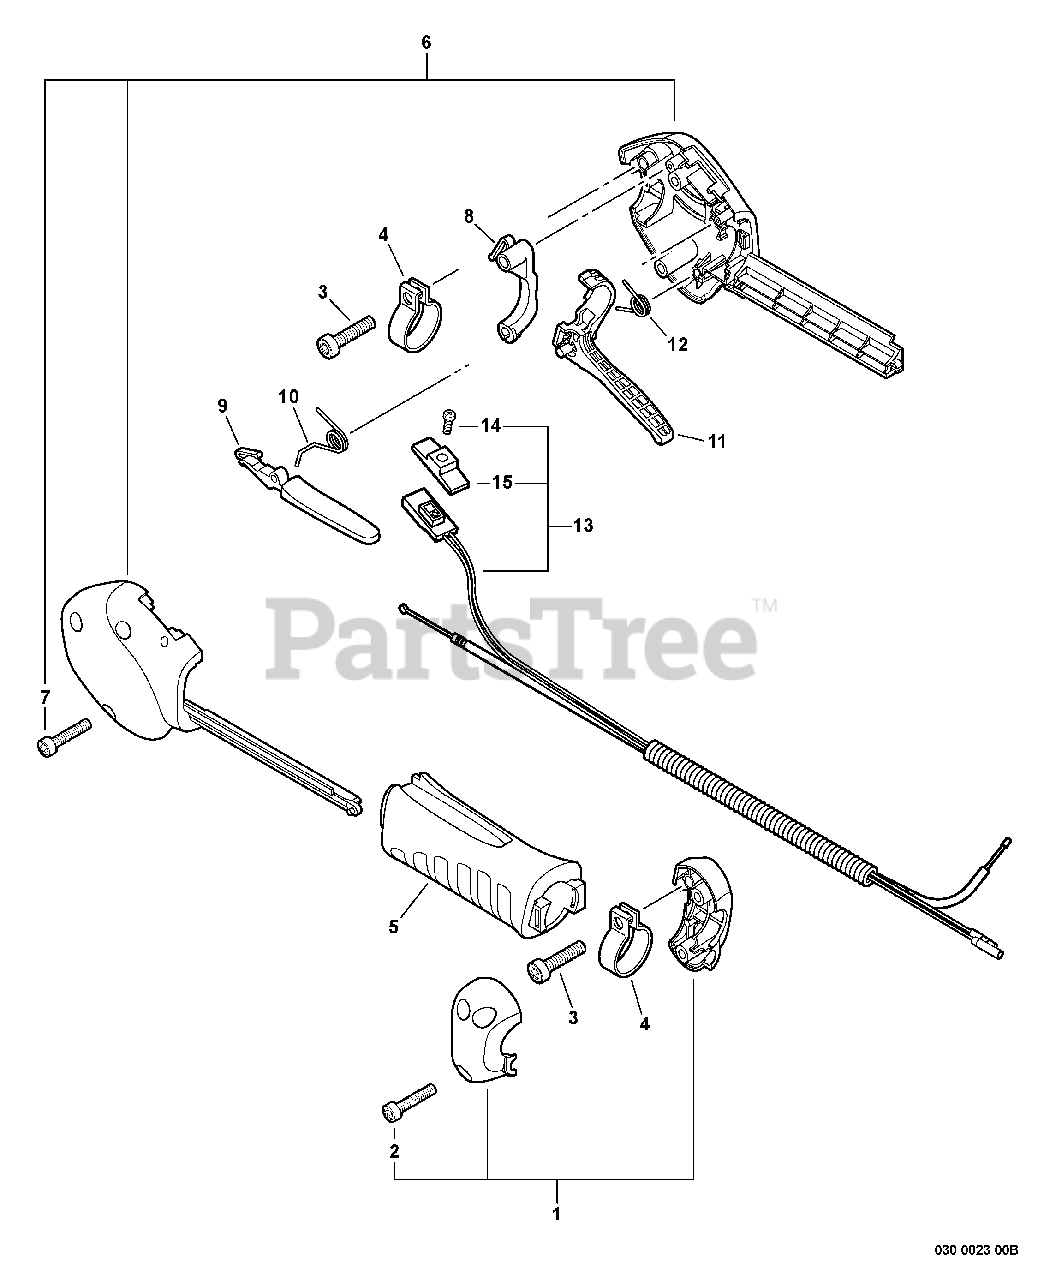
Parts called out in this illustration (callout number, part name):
1	FIXTURE SET, HANDLE
2	BOLT, TORX 4×20
3	BOLT, TORX 5×20
5	GRIP, HANDLE
6	HANDLE KIT, CONTROL
7	BOLT, TORX 4×20
8	LOCKOUT, THROTTLE
9	LEVER, THROTTLE LOCKOUT
10	SPRING, TORSION
11	TRIGGER, THROTTLE
12	SPRING, TORSION
13	CABLE ASSY, CONTROL
14	SCREW 3×10
15	KNOB, SWITCH - ORANGE
